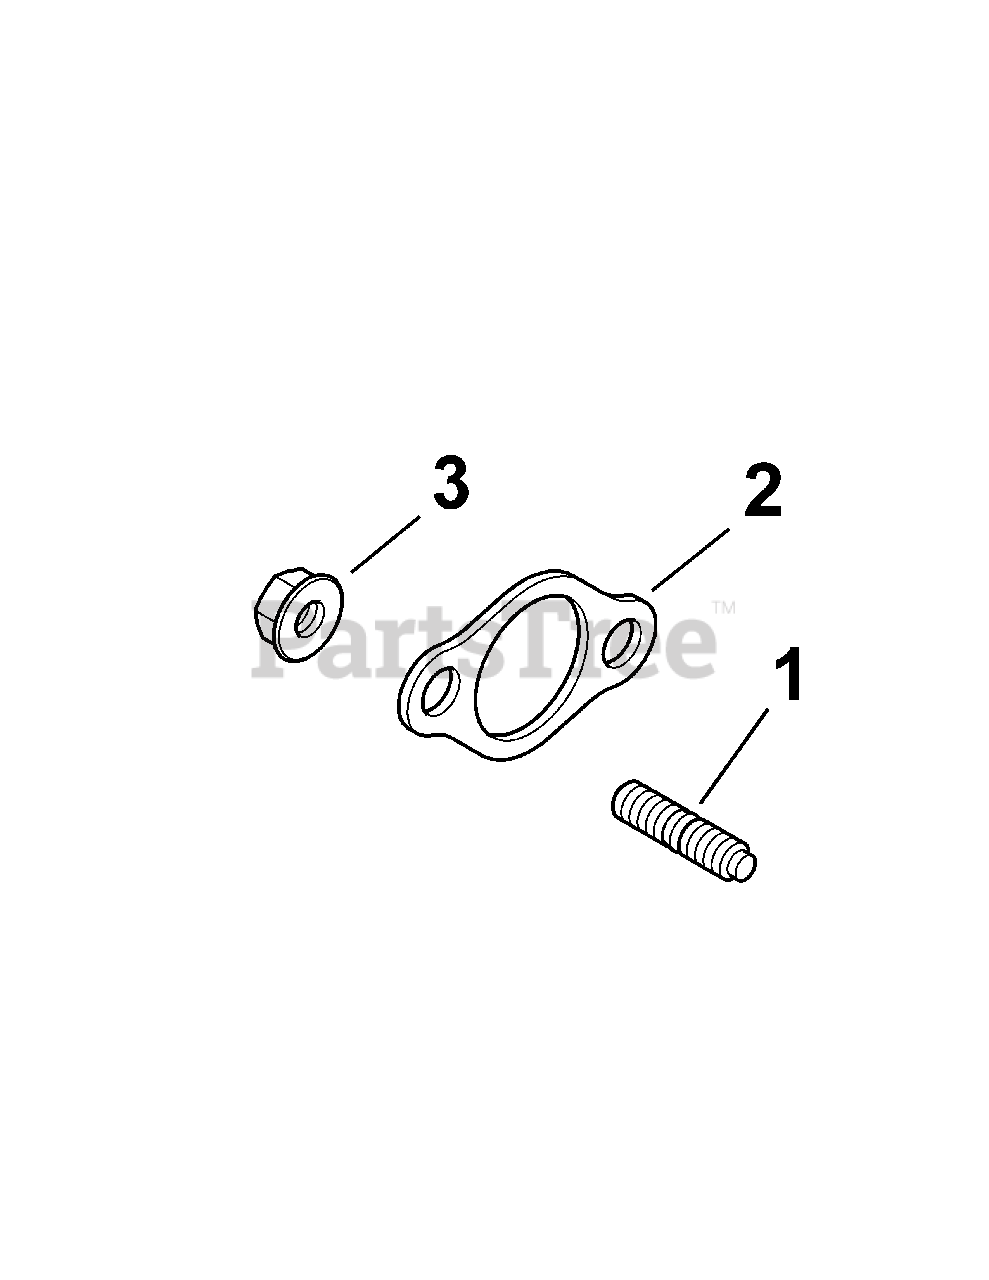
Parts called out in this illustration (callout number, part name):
1	STUD M8X1.25X33
2	GASKET, EXHAUST
3	NUT, FLG M8X1.25
